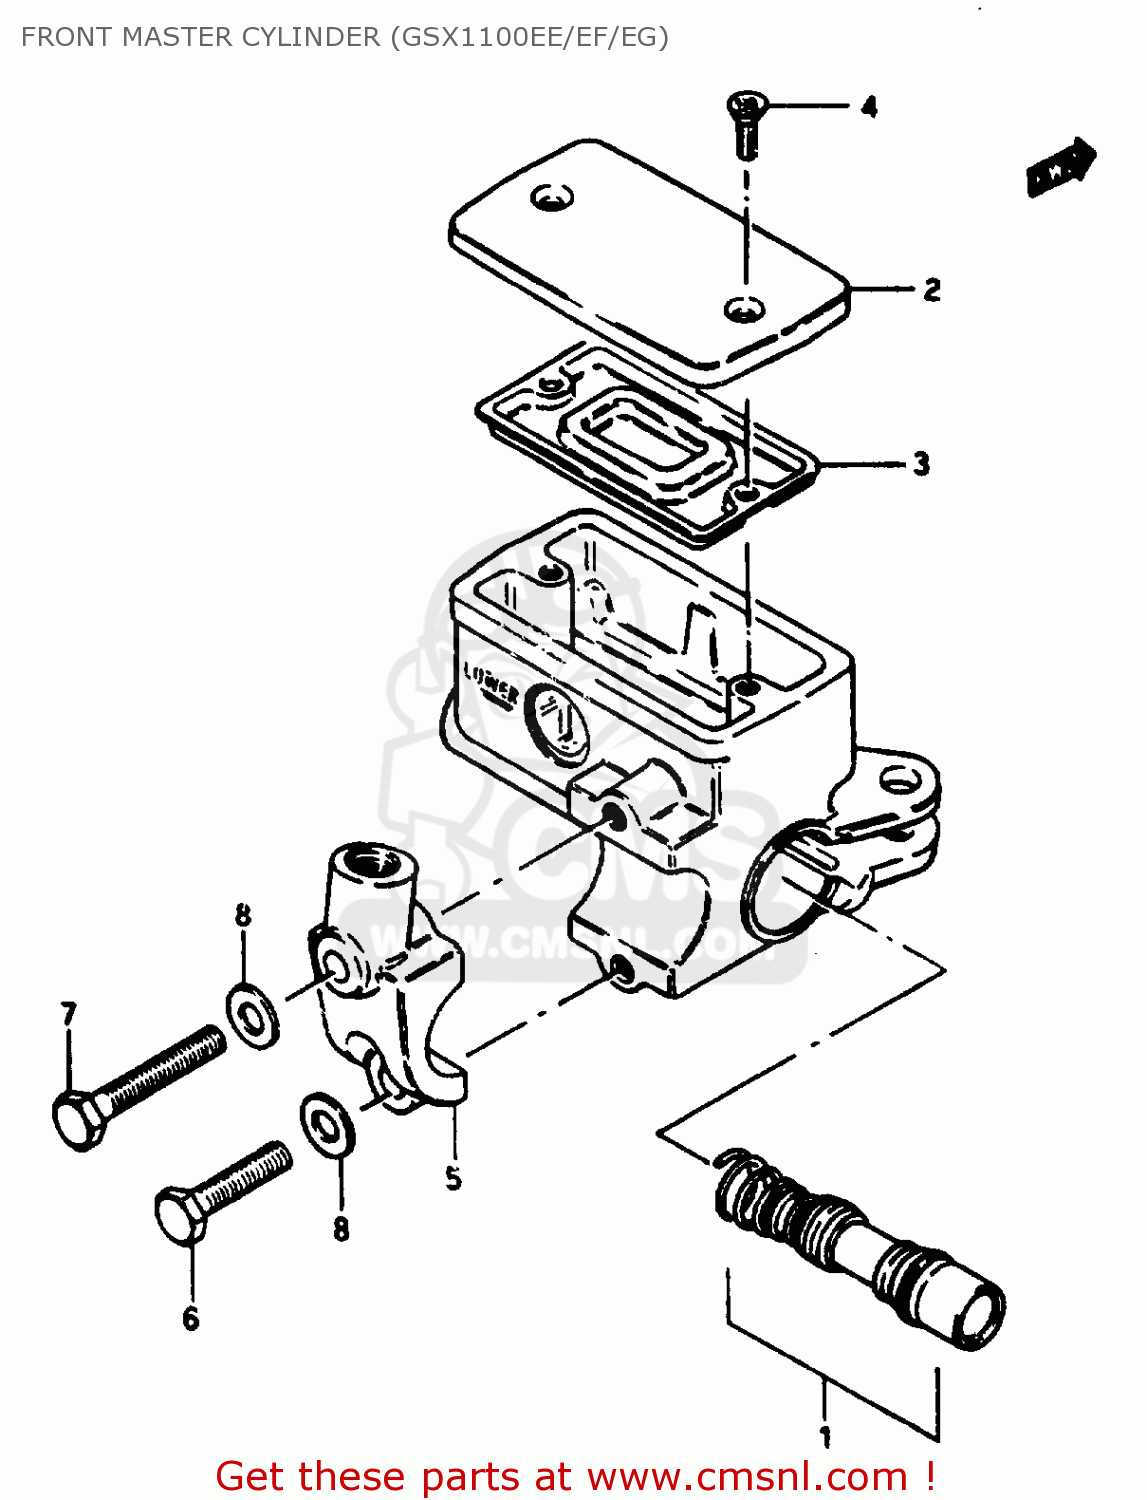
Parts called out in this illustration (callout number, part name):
1	PISTON & CUP SET
2	CAP
3	4
4	SCREW
5	HOLDER
6	BOLT
7	BOLT
8	WASHER
